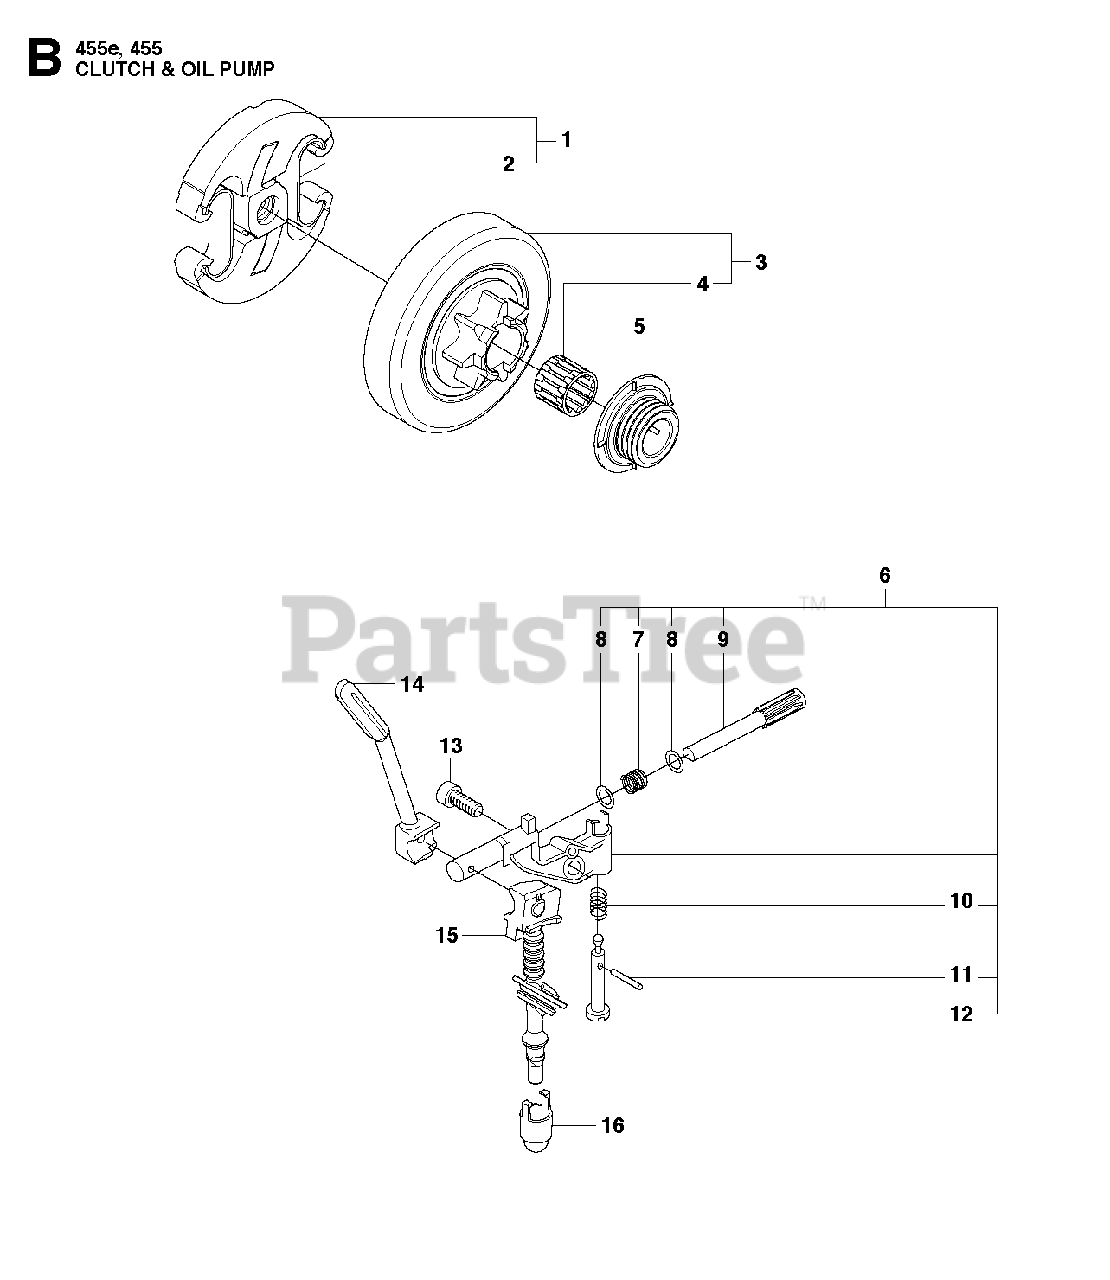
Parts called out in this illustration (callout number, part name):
2	SPRING
3	CLUTCH DRUM
4	NEEDLE BEARING
5	GEAR WORM OILER
6	OIL PUMP ASSY
7	SPRING
8	WASHER
9	PUMP PISTON
10	SPRING
11	PIN
12	ADJUSTER
15	RP OIL HOSE
16	OIL SCREEN
